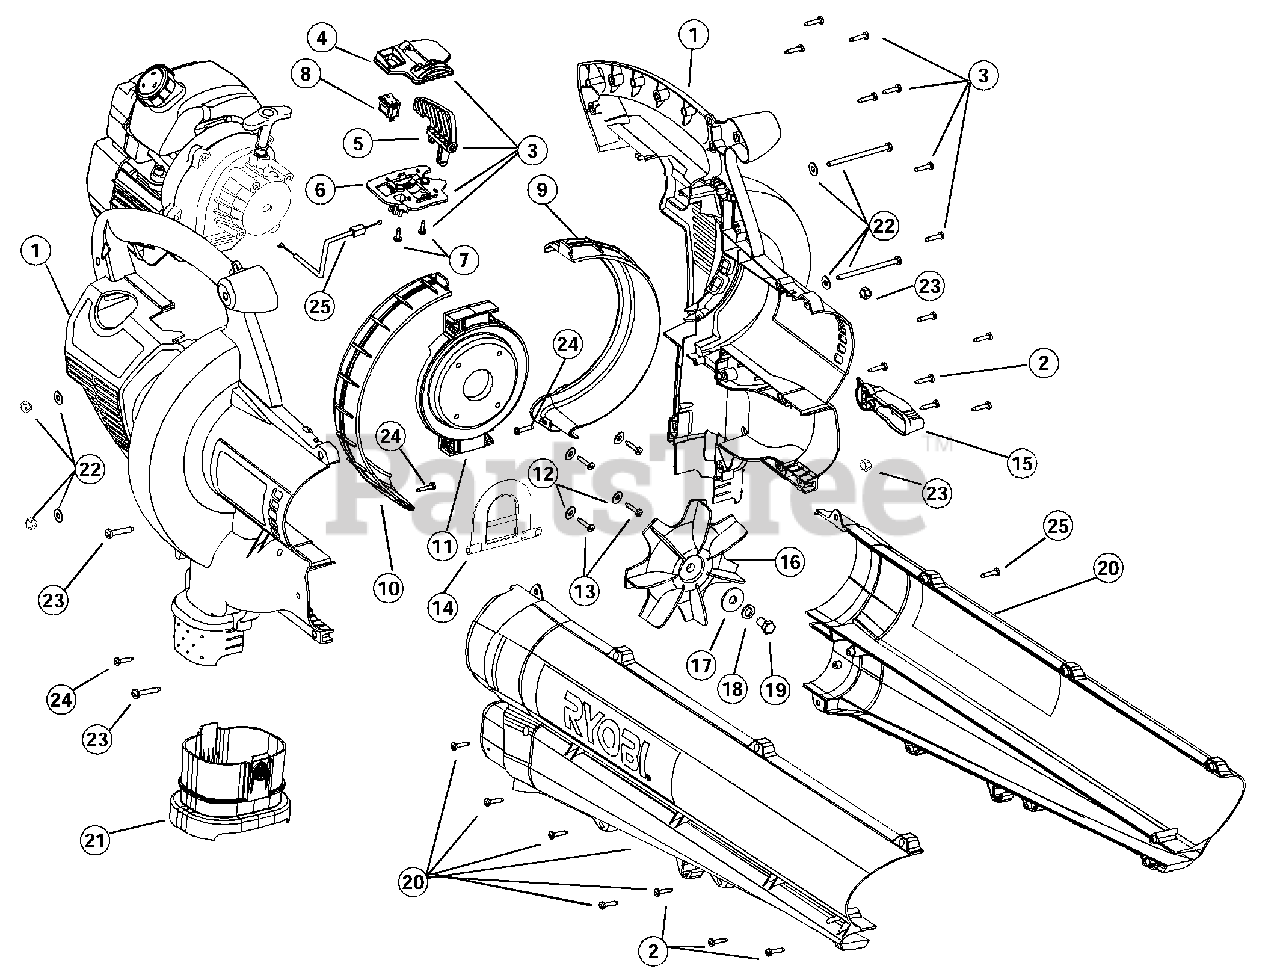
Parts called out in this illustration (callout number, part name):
1	Engine Cover Assembly
2	Cover Screw
3	Throttle Control Assembly
4	Upper Throttle Control Plate
5	Throttle Control Lever
6	Lower Throttle Control Plate
7	Screw, Plastic
8	Rocker Switch Assembly
9	Left Side Liner
10	Right Side Liner
11	Engine Mounting Plate
14	Mode Control Flapper
15	Mode Control Lever
16	Impeller Blade
17	Washer
18	Lock Washer
20	Blower/Vac Tube Assembly
21	Vacuum Bag Adapter
22	Mounting Plate Hardware
23	Blower/Vac Tube Mounting Hardware
25	Throttle Cable
